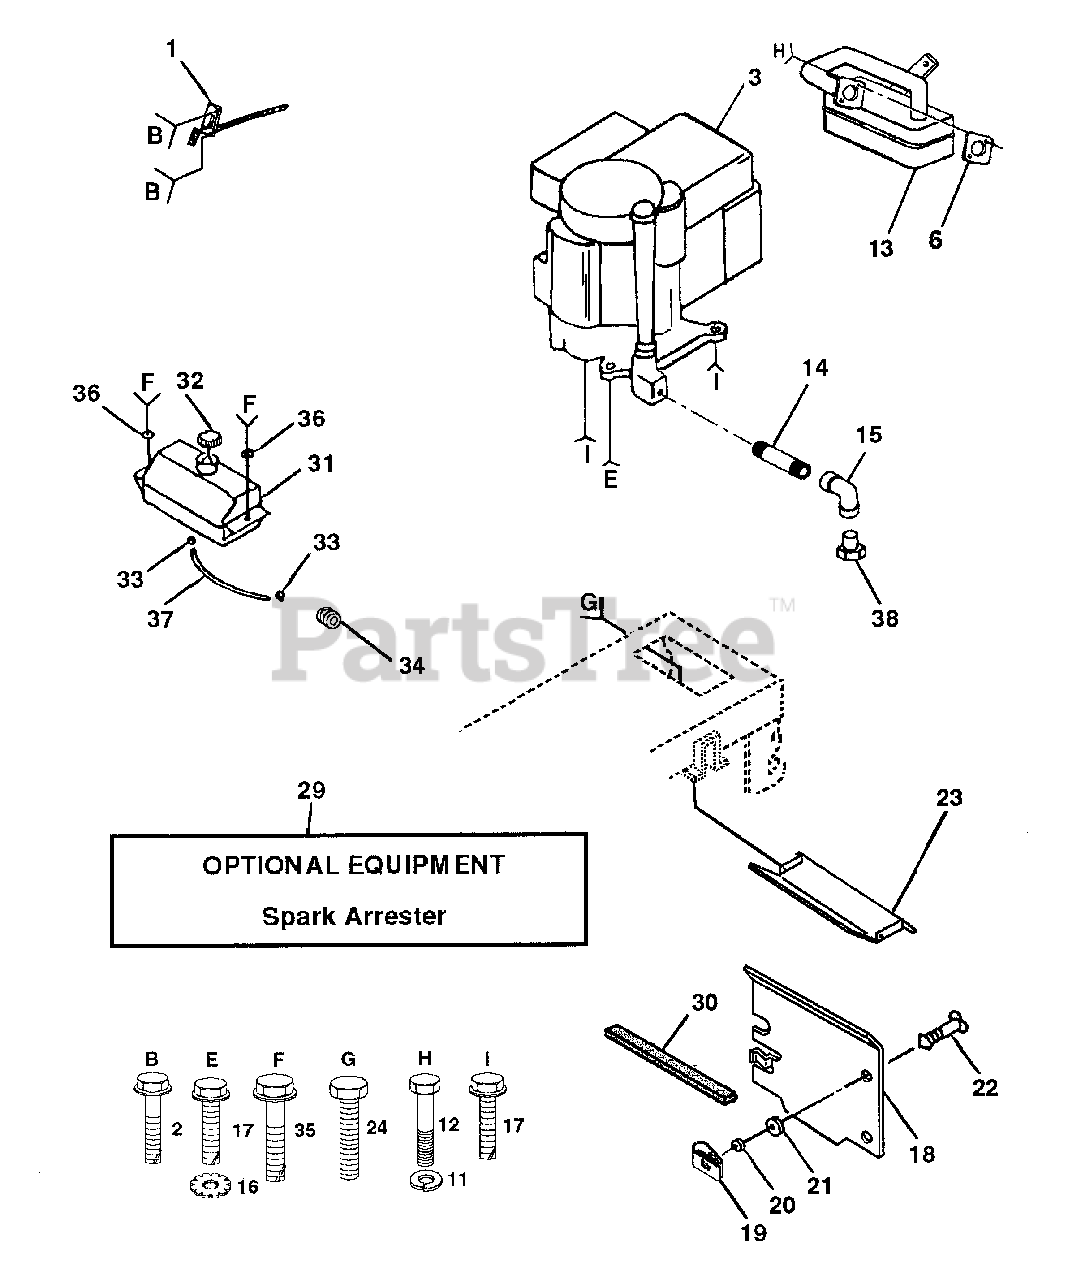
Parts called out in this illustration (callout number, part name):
1	Control Th/ch RH Blk Tee Eec
2	Screw Hex Thd Cut 1/4-20x5/8 T
6	Gasket Eng 1 313 Id Tin Plated
11	Washer Lock Hvy Hlcl Spr 5/16
12	Screw Hexhd Cap 5/16-18x3/4
13	Muffler LT B&s 12/12.5 HP
14	Nipple Pipe 3/8 Npt X 3"
15	Elbow Std 90 Degree 3/8-18 Npt
16	Washer Lock Ext Tooth 3/8
17	Screw Thdrol 3/8-16x1-1/4 TYTT
18	Shield Heat LT
19	Receptacle 1/4 Turn dacrotized
20	Retainer 1/4 Turn 365 OD x .222 ID
21	Washer 9/32 x 5/8 x 16 Ga
22	Stud 1/4 Turn
23	Shield Heat Browning LT/YT
24	Screw Tap Hex #10-24unc X 1/2
29	Kit Spark Arrestor 1 25
30	Pinch Weld Hood Black 2.00
31	Tank Fuel Front 2.00
32	Cap Asm Fuel W/sym Vented
33	Clamp Hose Blk
34	Bushing Snap Nyl Blk Fuel Line
35	Screw Hexwsh Thdrol 1/4-20x3/4
36	Washer 9/32 X 7/8 X 16ga
37	Line Fuel 9 20"
38	Plug Oil Drain
